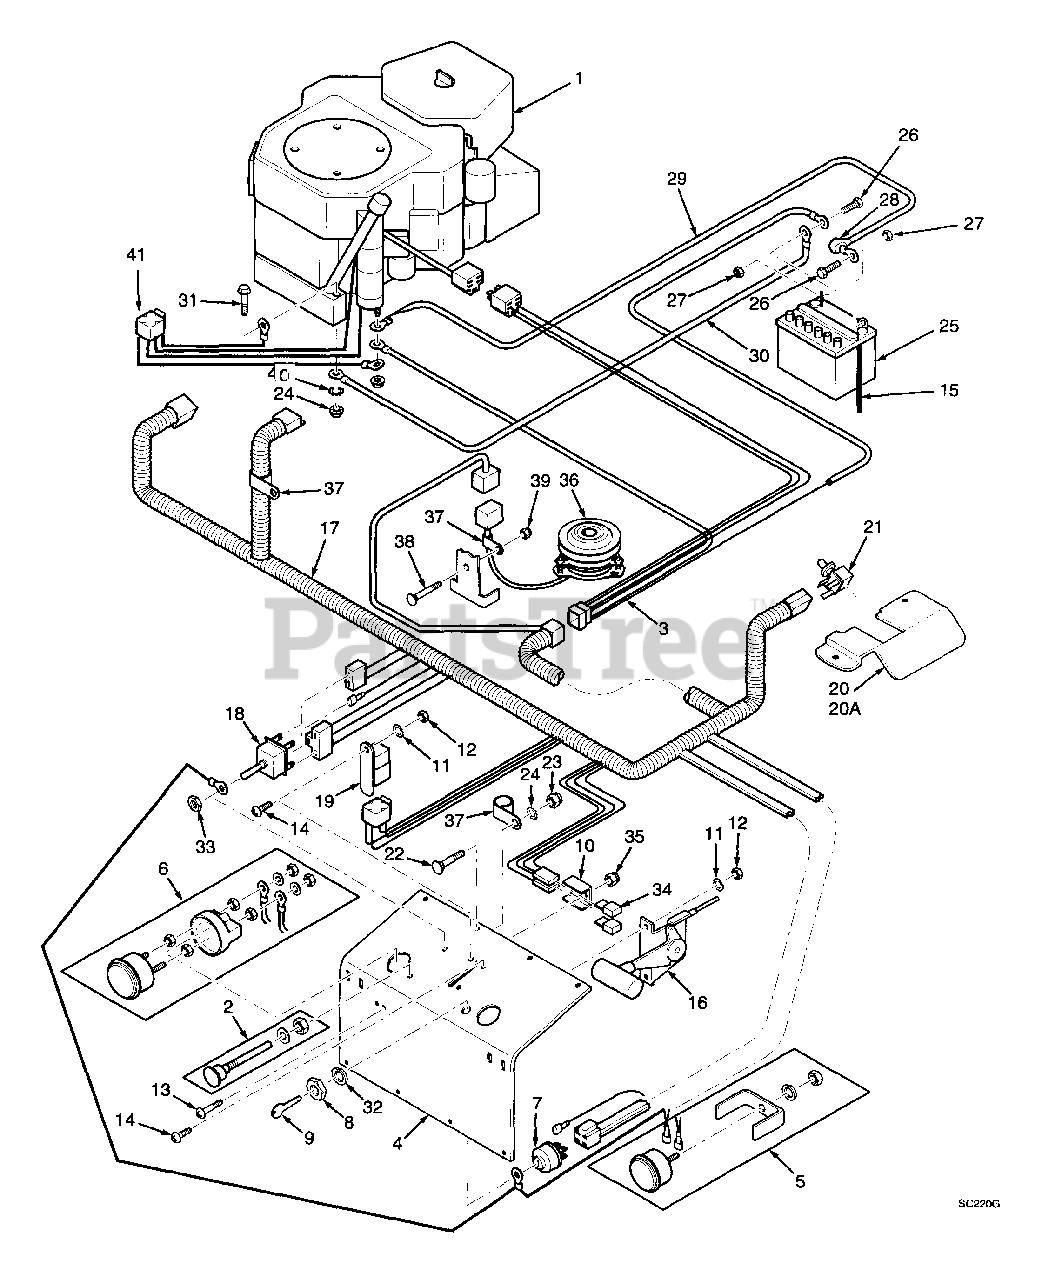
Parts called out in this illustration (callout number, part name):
1	Engine 18 hp Kohler CV
2	Choke Control
3	Adapter
4	Kick Plate
5	Hour Meter
6	Ammeter
7	Key Switch
8	Nut, Hex 5/8-32
9	Key & Ring Assembly
10	Bracket, Fuse Holder
11	Lockwasher, #10 External Tooth
12	Nut, Hex #10-32
13	Screw, Phillips Washer Head #10-32 x 1-1/2"
14	Screw, Phillips Washer Head #10-32 x 1/2"
15	Overflow Tube
16	Throttle Control
17	Wire Harness
18	Switch, Mower Engagement Electric Clutch
19	Relay
20	Neutral Lock Bracket, RH
20A	Neutral Lock Bracket, LH
21	Switch Neutral Lock
22	Bolt, Carriage 5/16-18 x .75"
23	Nut, Elastic Stop 5/16-18
24	Nut, Serrated Flange Hex 5/16-18
25	Battery
26	Bolt, Hex Head 1/4-20 x 1/2"
27	Nut, Hex 1/4-20
28	Rubber Boot
29	Battery Cable, 25" Red
30	Battery Cable, 27" Black
31	Bolt, Serrated Flange Hex Head 5/16-18 x 1.50"
32	Lockwasher, 5/8" Internal
33	Nut, Hex 1/2-27
34	Fuse, Blade Type 20 amp
35	Nut, Elastic Stop #10-32
36	Electric Clutch
38	Bolt, Carriage 5/16-18 x 3/4"
39	Nut, Elastic Stop 5/16-18
40	Lockwasher, 5/16" Internal Tooth
41	Wire Harness W/Relay
